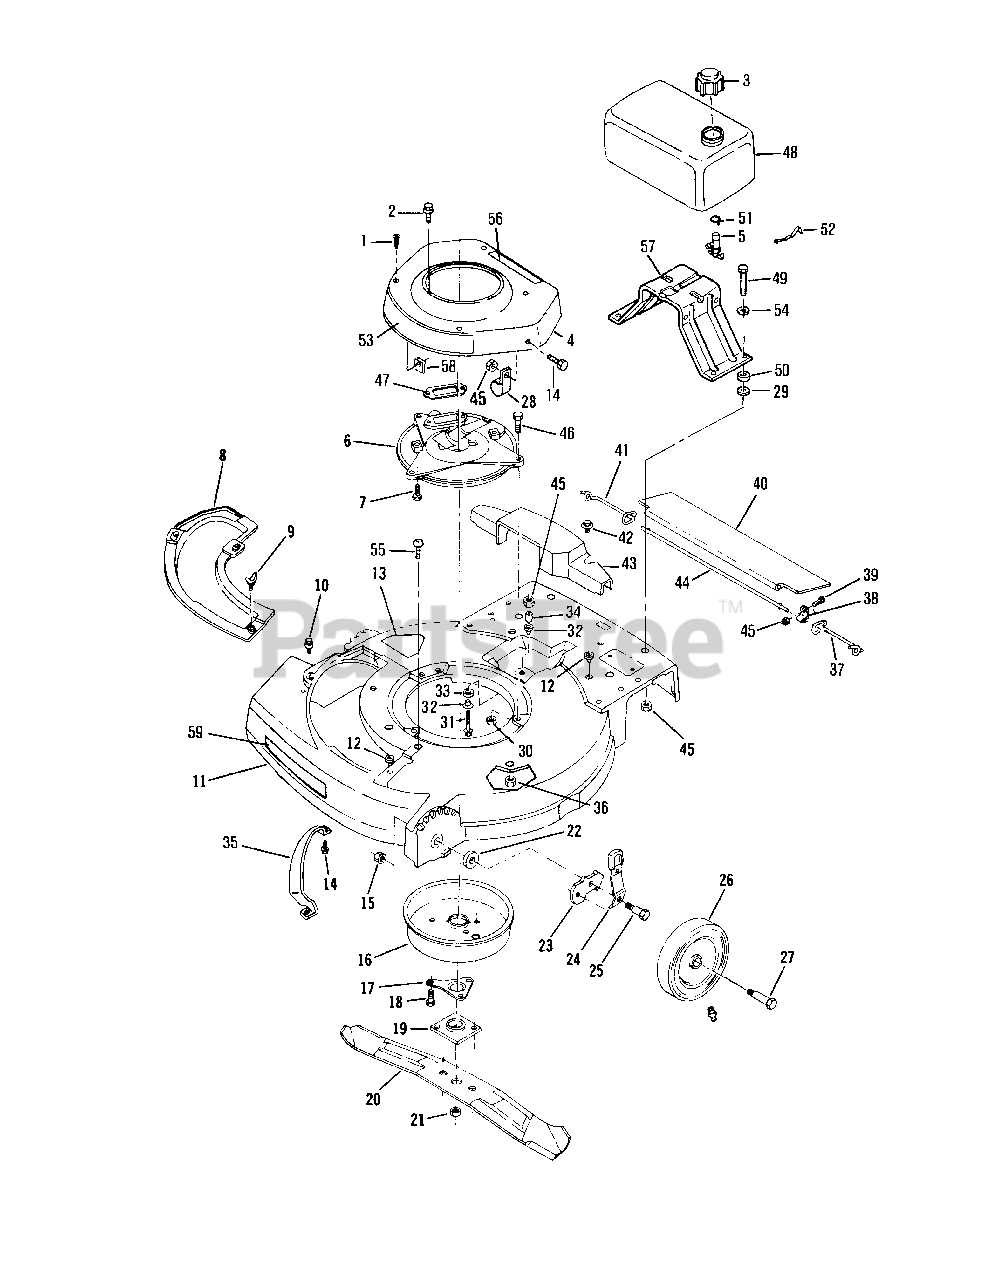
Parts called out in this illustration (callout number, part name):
1	Screw
2	Screw
3	Fuel Cap
4	Shroud-Engine
5	Fuel Shut-Off Assembly
6	Plate-Muffler
7	Screw-Muffler Plate to Block
8	Cover Plate
9	Wing Screw
10	Screw-Plate and Chute Mounting
11	Housing
12	Grommet
13	Decal-Blade Contact Warning
14	Screw
15	Nut
16	Muffler Cover Assembly
17	Support-Crankshaft
18	Screw-Muffler to Muffler Plate
19	Collar and Plate Assembly
20	Blade-21"
21	Nut-Blade
22	Washer
23	Bracket-Wheel Height Adjust
24	Knob and Spring Assembly
25	Bolt-Shoulder
26	Wheel-Front
27	Bolt-Wheel-Front
28	Clamp
29	Washer
30	Nut-Muffler Plate to Housing
31	Screw
32	Spacer
33	Grommet
34	Spacer
35	Toe Bar
36	Locknut
37	Spring-L.H.
38	Clamp
39	Screw
40	Shield-Trailing
41	Spring-R.H.
42	Screw-Axle Cover Mounting
43	Cover-Drive Axle
44	Rod-Trailing Shield
45	Nut
46	Screw-Muffler Plate to Housing
47	Gasket-Exhaust
48	Fuel Tank
49	Bolt
50	Grommet
51	Clamp
52	Spring
53	Decal
54	Washer Tank Mounting
55	Bolt
56	Decal-Fuel Mix
57	Bracket-Tank Mounting
58	Retainer
